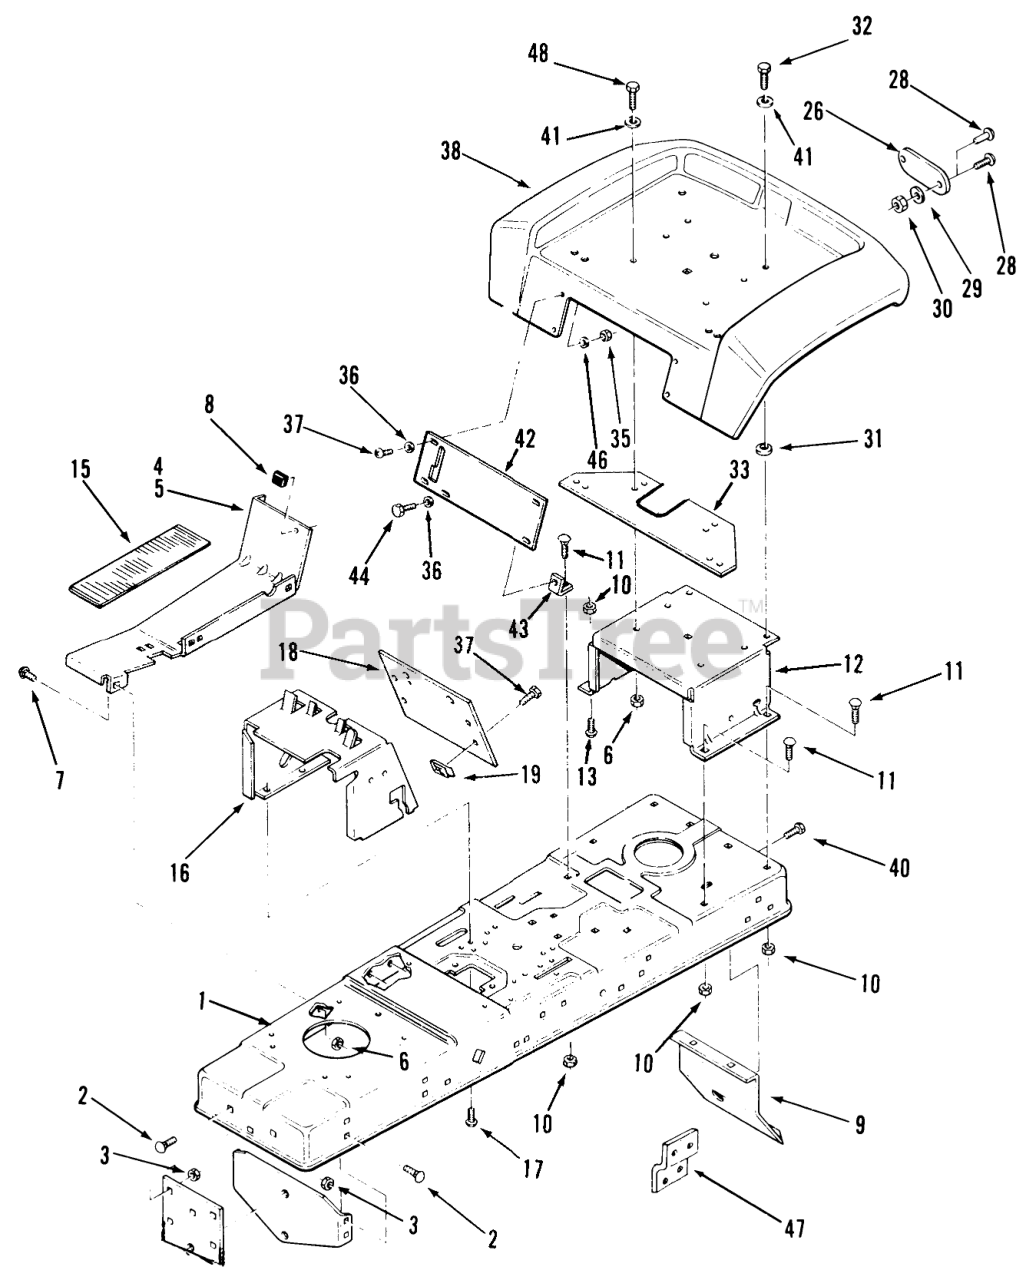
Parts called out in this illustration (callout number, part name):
1	Frame
2	Bolt
3	Nut
4	FOOTREST-R.H. R
5	FOOTREST-L.H. R
6	Nut
7	Bolt
8	BUMPER
9	Hitch-Drawbar
10	Nut
11	Bolt
12	Support-Seat
13	CARRIAGE BOLT -4
15	PAD-FOOTREST
15	MAT-FOOTREST R.H.
15	MAT-FOOTREST L.H.
16	Hoodstand
17	SCREW
18	Hoodstand Plate 252-H
18	PLATE-HOODSTAND R B
26	Reflector
28	Poprivet
28	Screw
29	Lockwasher
30	Nut
31	WASHER
32	Bolt
33	PLATE-SEAT R
35	Nut
37	Screw
38	FENDER R
40	Bolt
41	WASHER 5/16 SAE
42	Front Fender Plate
43	BRACKET FENDER
44	Bolt
46	Washer
47	BRKT SWITCH BRAKE R
48	Bolt-Carriage
